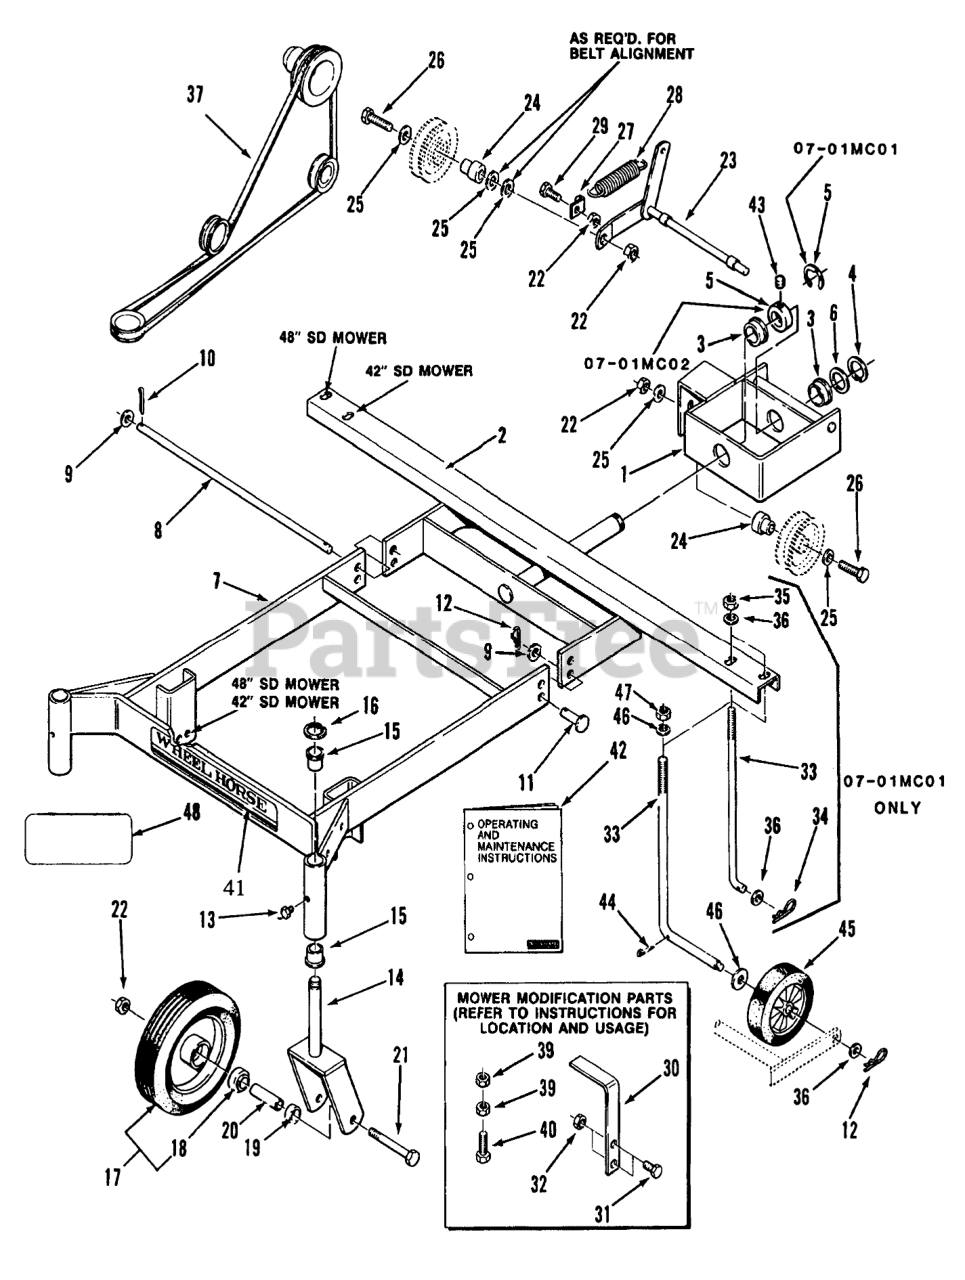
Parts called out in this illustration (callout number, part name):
1	Hitch Frame (07-01MC01,02)
2	Pivot Frame (07-01MC01)
3	BUSHING
4	Snap Ring
5	Collar
7	ASSY FRAME R
8	PivotRod
9	Washer
11	CLEVIS PIN
12	Hairpin Cotter
13	Zerk
14	ASSY SWIVEL CASTE R
15	BUSHING
16	RING-SNAP, EXTERNAL
17	Gage Wheel 8 x 2.50
18	Ball Bearing
19	SPACER
20	SPACER
21	Bolt 3/8-16 x 4
22	NUT
23	ASSY BELT ADJ R
24	SPACER
25	Washer
26	Bolt
27	CLIP - SPRING
28	SPRING-EXTENSION
29	BOLT
30	HANDLE-EXTENSION R
31	Bolt
32	Nut
33	Rod
34	Hairpin
35	NUT
36	Washer
37	BELT MOWER DRIVE
39	NUT-HEX, JAM
40	Bolt
41	DECAL WHEEL HORSE
42	Operating And Maintenance Instructions
43	Screw-Set
44	Cotter Pin
45	WHEEL ASM
46	Washer
47	Nut
48	DECAL-OVERLAY
